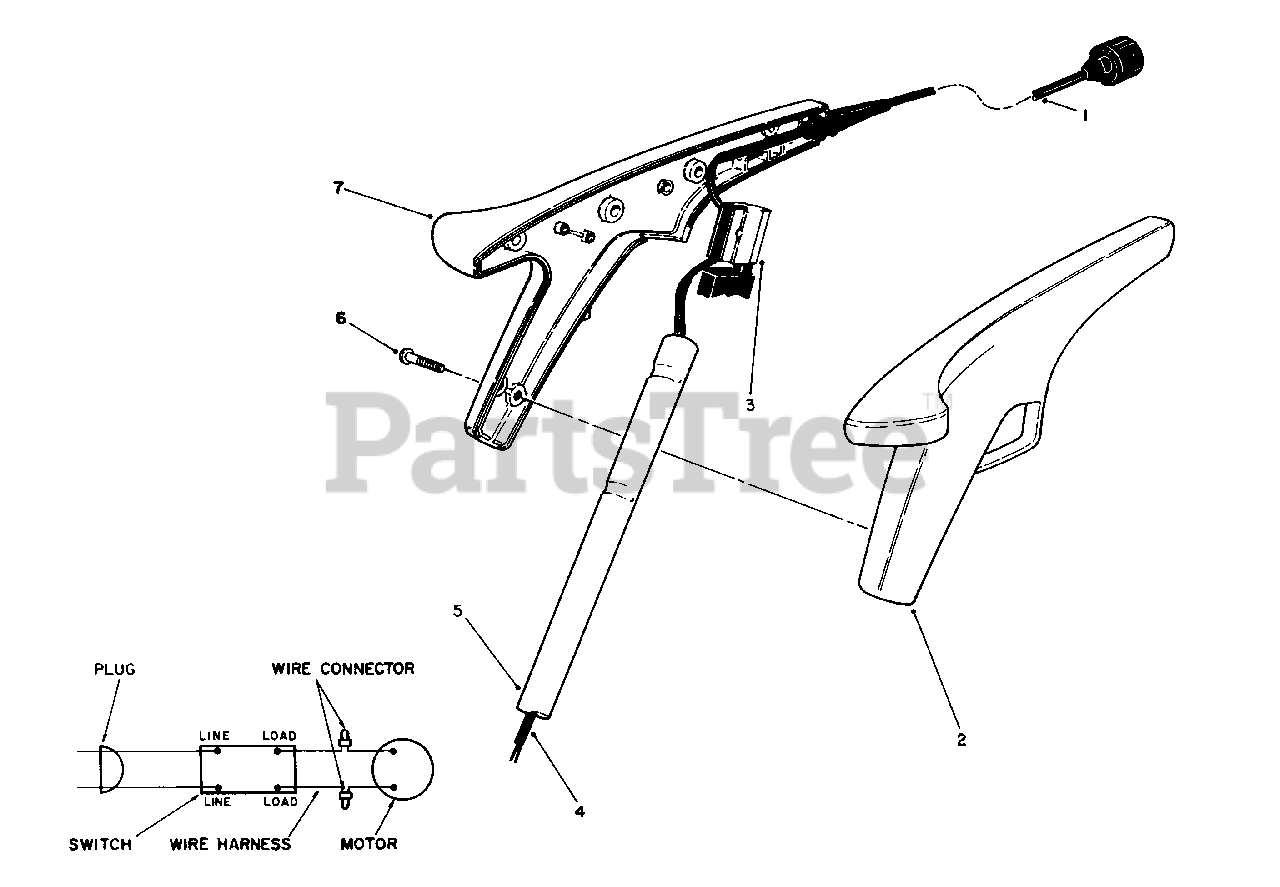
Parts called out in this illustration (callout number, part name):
1	Cord-Power
2	Grip-L.H.
4	Harness-Wiring
7	Grip-R.H.
